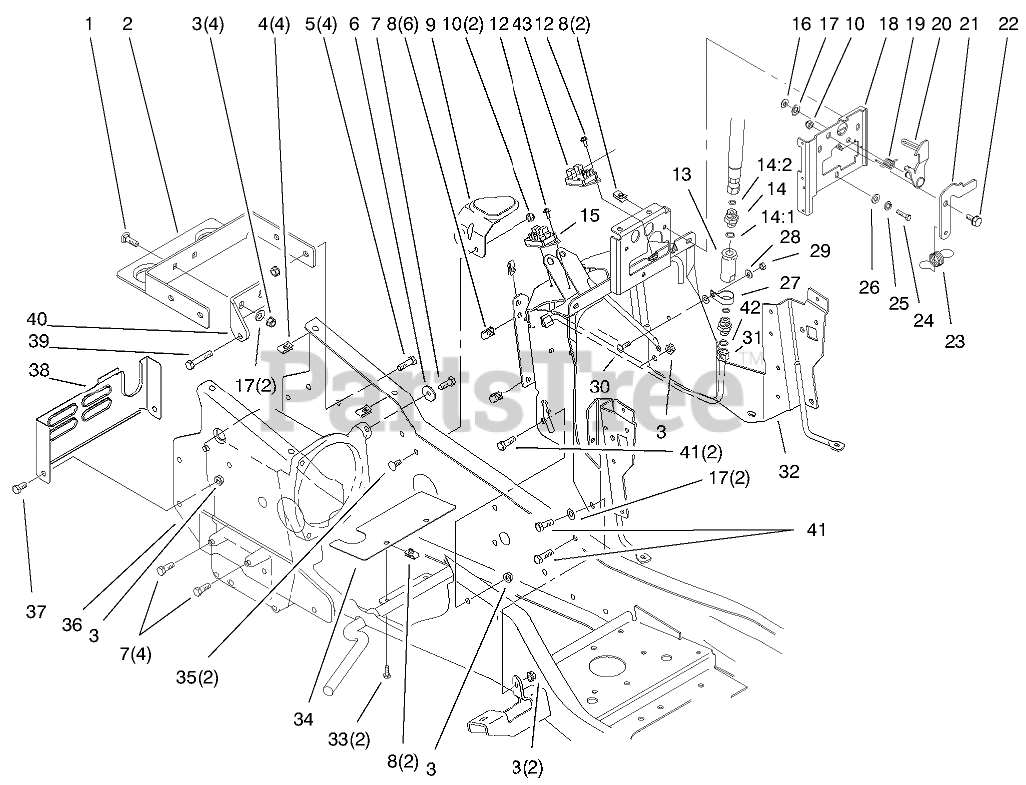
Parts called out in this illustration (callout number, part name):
1	BOLT-CARR
2	Support-Gas Tank
3	NUT-LOCK, NI
4	NUT-U
5	SCREW-HH
6	WASHER
7	SCREW-HH, LOCK
9	SUPPORT-TANK, FUEL
10	NUT-LOCK, NI
11	MODULE-OVER TEMP
12	SCREW
13	FILTER-SCREEN, HYD
14	FITTING-HYD. STRAIGHT
14:1	O-RING
14:2	O-RING
15	MODULE-CRUISE
16	RING-RETAINING
17	WASHER-FLAT
18	BRACKET-LATCH
19	SPRING-LEVER, LATCH
20	LEVER-LATCH
21	LATCH-LEVER, TENSION
22	BOLT-SHOULDER
23	SPRING-LEVER, LATCH
24	SCREW-HH
25	WASHER-LOCK
26	WASHER-FLAT
27	CLAMP-R
28	WASHER-FLAT
29	NUT-LOCK, NI
30	BOLT-CARR
31	TUBE-HYD
32	TOWER ASM
33	SCREW-HH
34	BAFFLE-FAN
35	SCREW-CARR
37	SCREW-HH
38	COVER-REAR
39	SCREW-HH W/LOCTITE
40	Strap-Torque
41	SCREW-HH
42	PUSHNUT-RETAINER, BOLT
43	MODULE-CLUTCH
